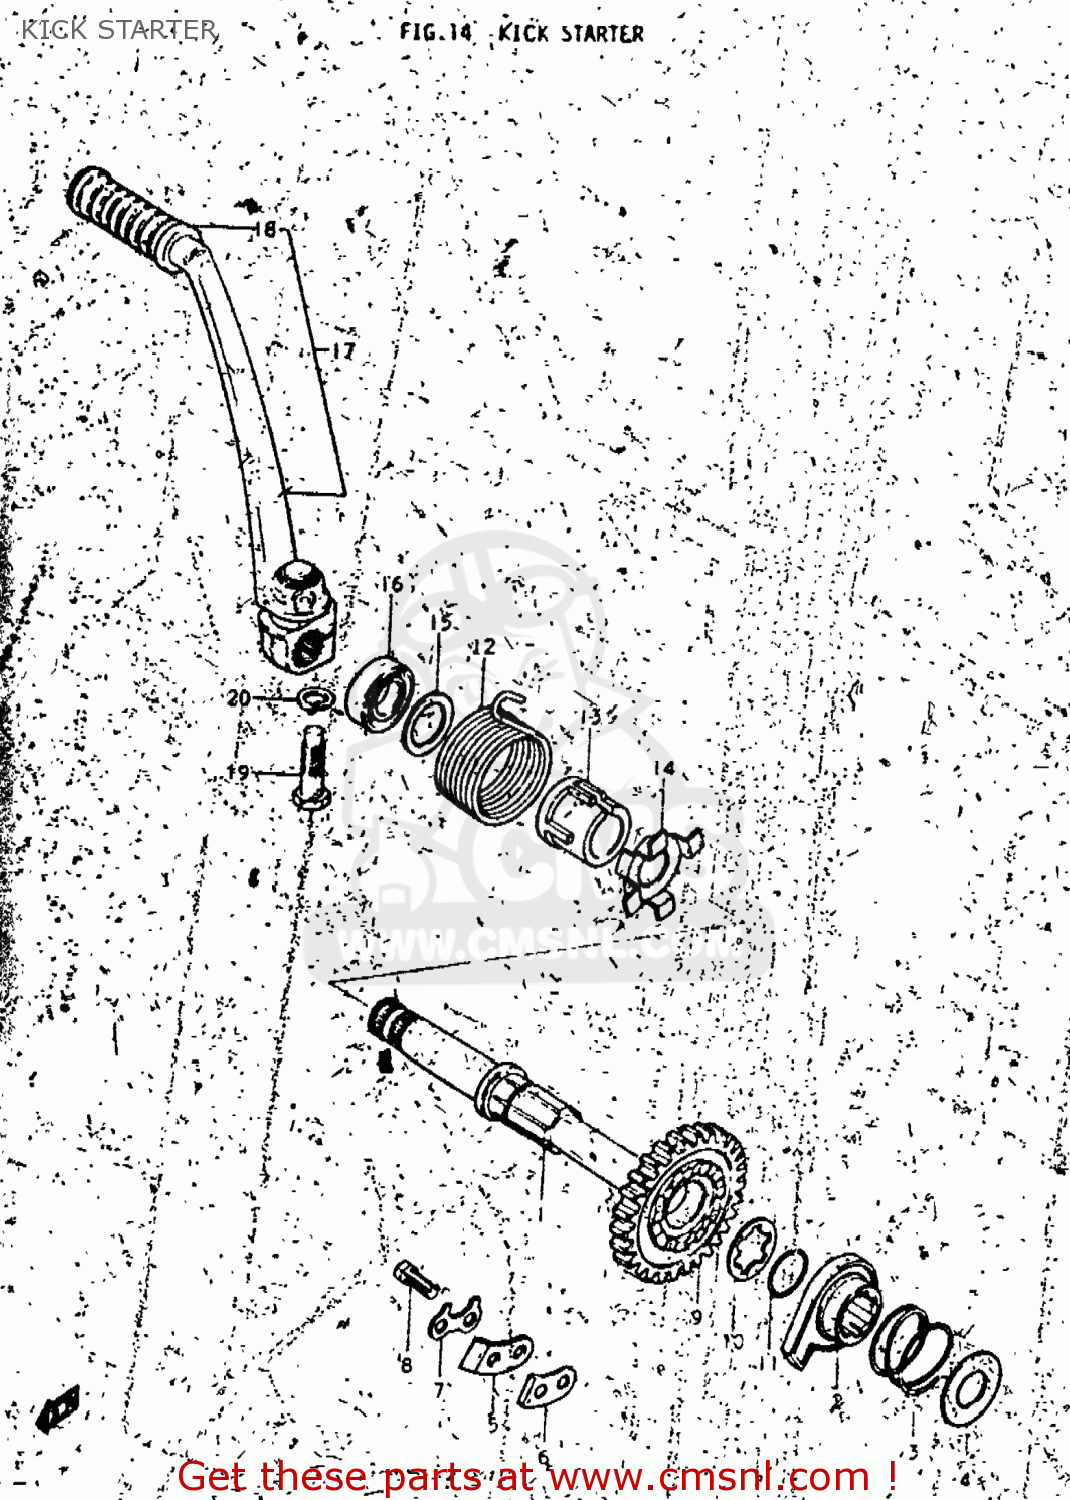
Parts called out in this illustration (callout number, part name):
1	SHAFT,KICK STARTER
2	STARTER,KICK
3	SPRING
4	WASHER
5	GUIDE,KICK STARTER
6	STOPPER,KICK STARTER
7	WASHER
8	BOLT
9	GEAR,KICK STARTER DRIVE
10	WASHER,LOCK
11	CIRCLIP
12	SPRING
13	GUIDE,KICK SHAFT SPRING
14	HOLDER,KICK SHAFT SPRING
15	WASHER
16	SEAL,OIL(20X37X7)
17	LEVER ASSEMBLY,KICK STARTER
18	RUBBER,KICK STARTER PEDAL
19	BOLT(10X37.5)
20	LOCK WASHER
